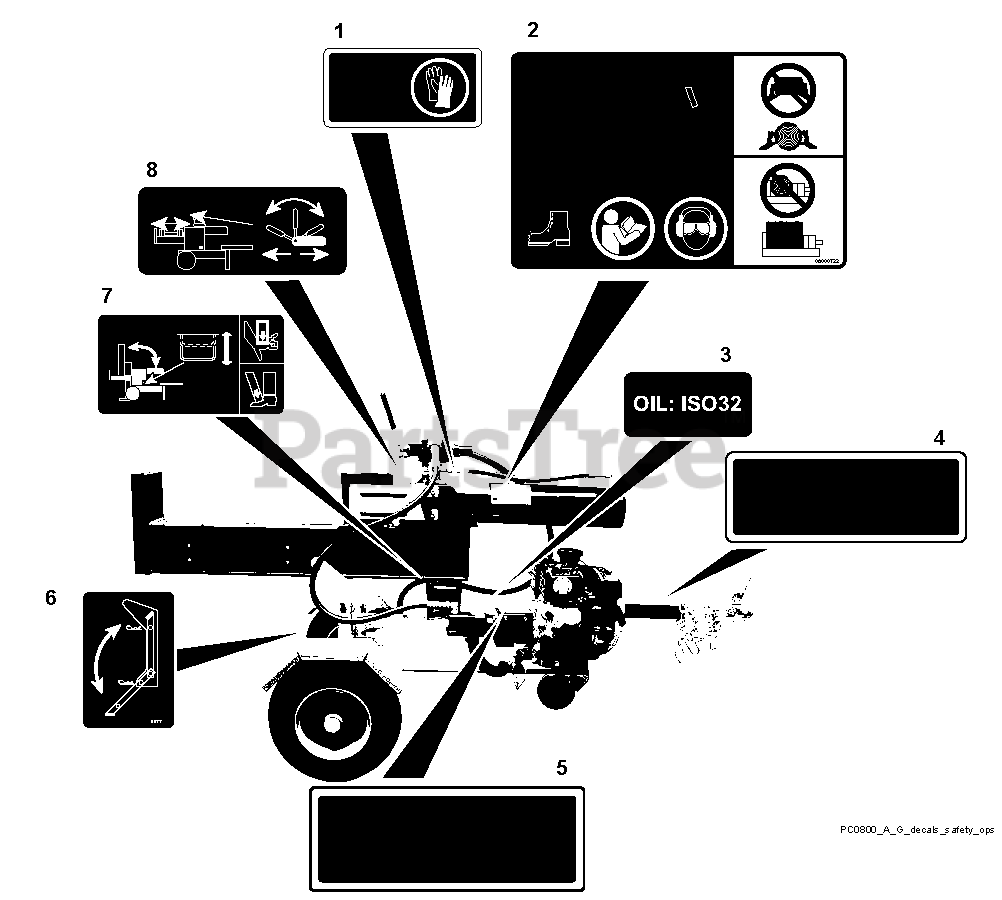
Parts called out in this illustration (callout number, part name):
1	Decal, Hydraulic Warning
2	Decal, Danger Log Splitter
3	Decal, Log Splitter Hydraulic Oil
4	Decal, Towing
5	Decal, Fuel Warning
6	Decal, Log Splitter Rear Stand
7	Decal, Log Splitter Tilt Operation
8	Decal, Log Splitter Ram Operation
